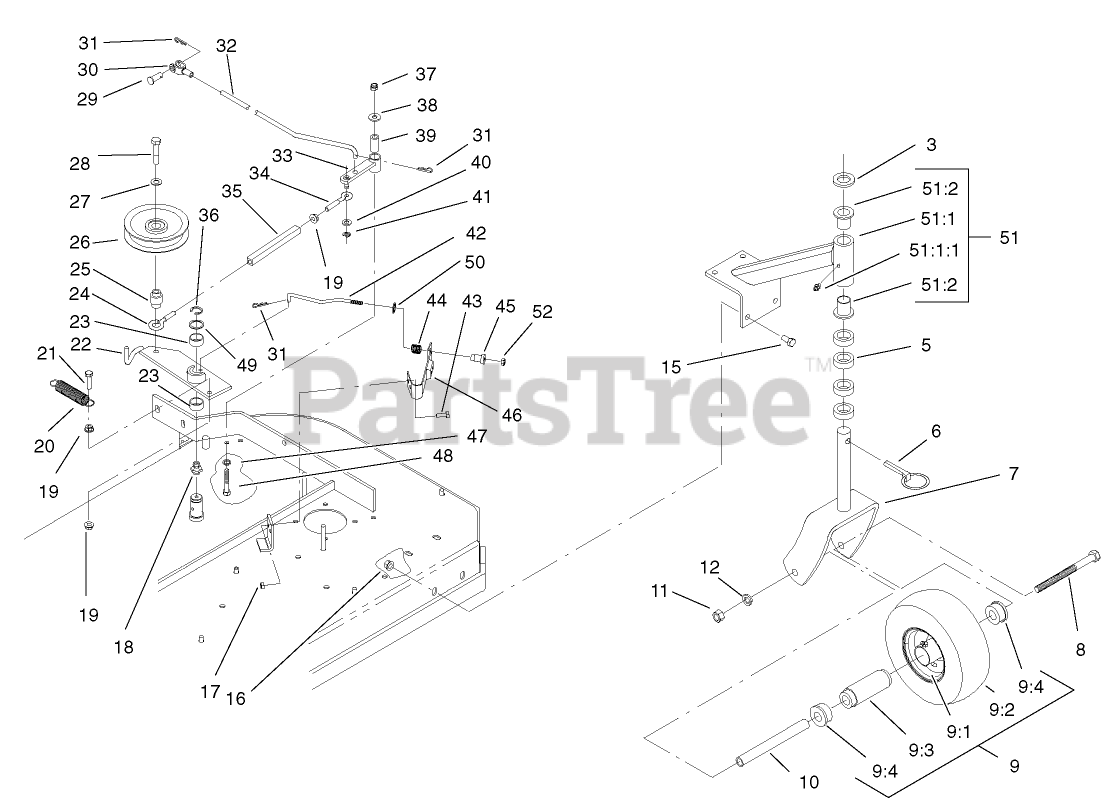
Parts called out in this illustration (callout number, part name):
3	WASHER-FLAT
5	SPACER-CASTER
7	FORK
8	SCREW-HH
9	WHEEL AND TIRE ASM
9:1	Rim
9:3	BEARING
9:4	BUSHING
10	SPACER
11	NUT-HH
12	WASHER-LOCK
15	SCREW-HH
16	NUT-HHF, WHIZ
17	NUT-LOCK, NI
18	FITTING-GREASE
19	NUT-HF
20	SPRING-EXTENSION
21	SCREW-HH
22	ASM,IDLER ARM/BUSHINGS
23	SLEEVE-BEARING
24	EYEBOLT-THREAD, LH
25	BUSHING-ENGAGEMENT
26	PULLEY-IDLER
27	WASHER-BELLEVILLE
28	SCREW-HH
29	PIN-CLEVIS
30	YOKE-ADJUSTABLE
31	PIN-COTTER
32	ARM-ASSIST, LINKAGE
33	ARM-ASSIST
34	EYEBOLT-THREAD, RH
35	BODY-TURNBUCKLE
36	RING-RETAINING, EXT
37	NUT-LOCK, NI
38	WASHER-FLAT
39	TUBE-PIVOT
40	WASHER-PLAIN
41	RING-RETAINING, EXT
42	ROD-BRAKE
43	SCREW-HH
44	SPRING-COMPRESSION
45	SPACER-FLANGED
46	PAD AND SPRING ASM
47	WASHER-SPRING
48	SCREW-HH
49	WASHER-SPINDLE
50	RING-PUSH ON
51	SUPPORT ASM
51:1	SUPPORT-CASTER
51:1:1	FITTING-GREASE
51:2	BEARING-FLANGED
52	NUT-LOCK, NI
